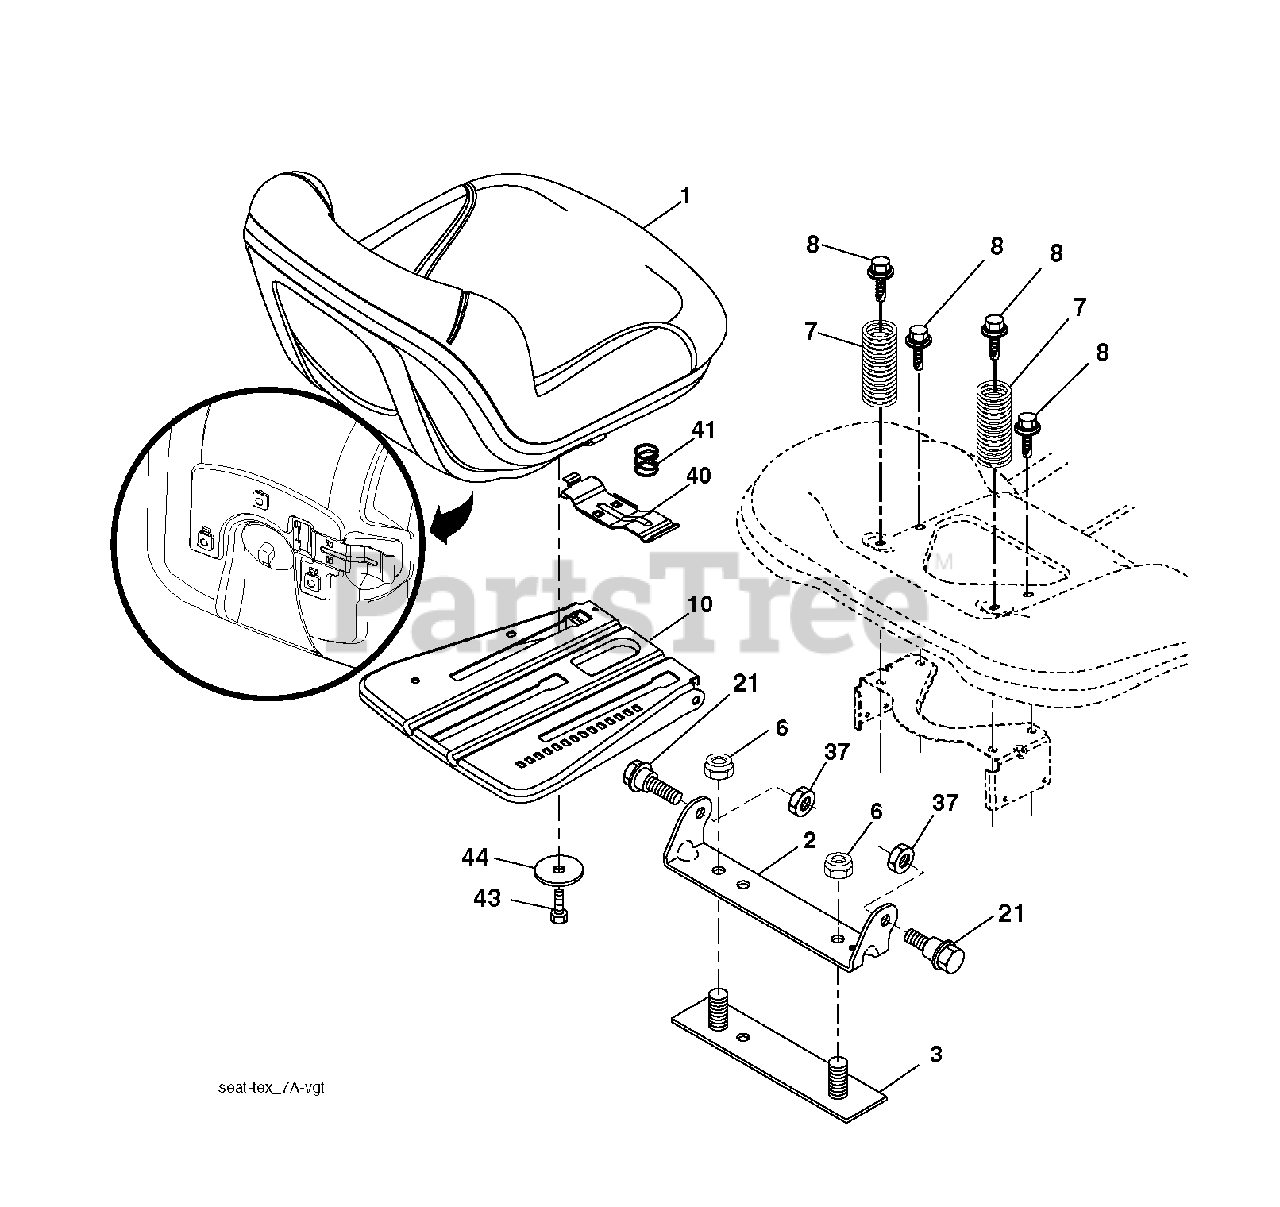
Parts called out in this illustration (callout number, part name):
1	SEAT.TH150.MS498.GRY.HUSQ.TEX
2	BRKT.PIVOT.FENDER
3	STRAP
6	NUT
7	SPRING COMPRESSION
8	BOLT, 5/16-18 X 1 3/4
10	PAN.ASM.SEAT.3PT
21	BOLT.SHOULDER.5/16-18
37	NUT.71038.31-18.HEX.NYLOCK
40	HANDLE.SLIDE.SEAT.TEX.BLACK
41	SPRING.LATCH.SEAT.TEX
44	WASHER 13/32 X 2-3/8 X 12GA
